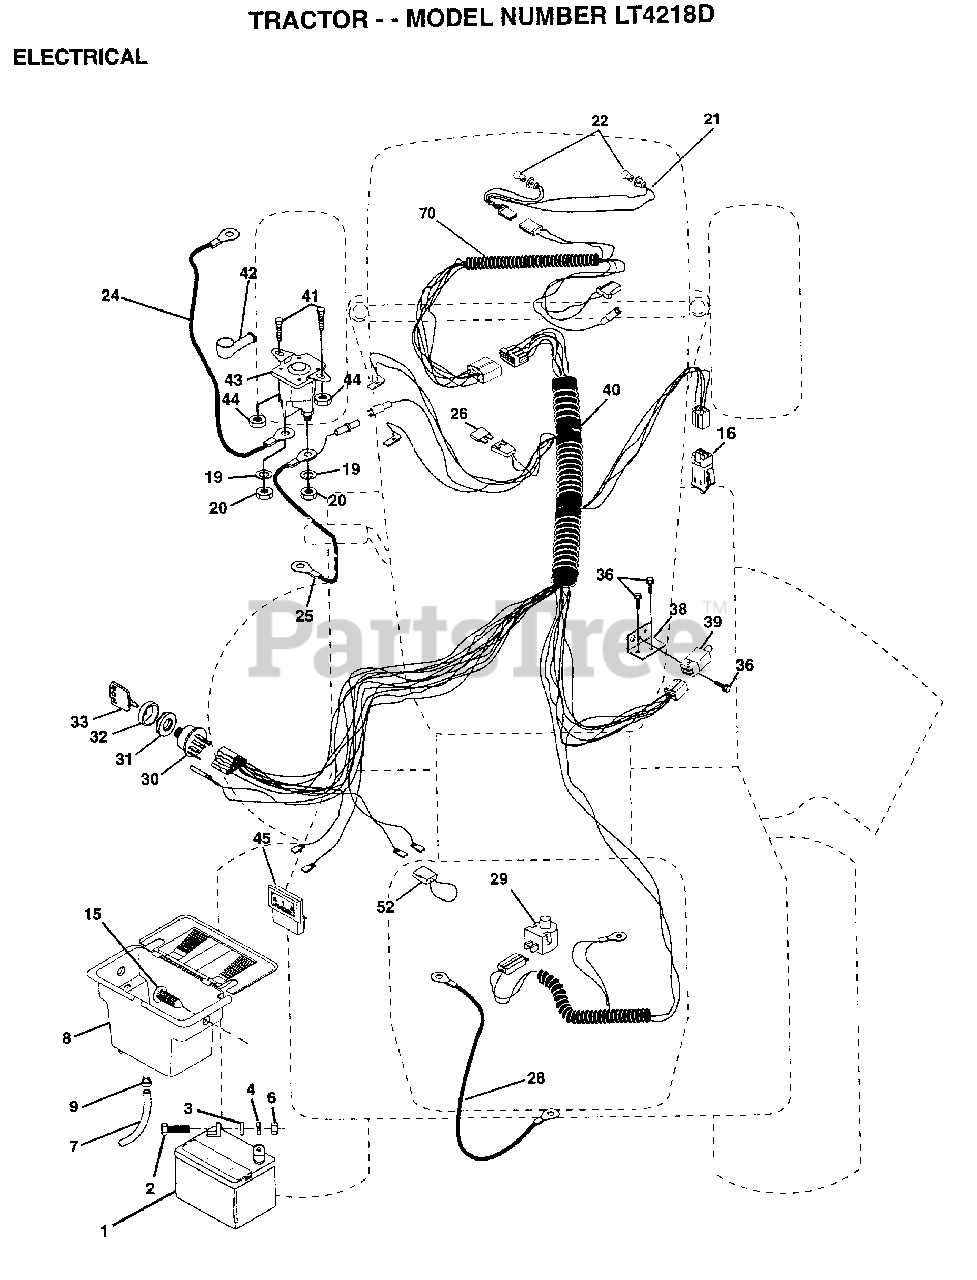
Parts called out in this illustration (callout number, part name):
2	BOLT LT
3	WASHER
4	LOCKWASHER
7	TUBE T
9	HOSE CLAMP T
15	FASTNER.SNAP-IN
16	SWITCH INTERLOCK
20	NUT
21	"HARNESS,LIGHT SOC"
22	HEADLAMP BULB
24	CABLE-BATTERY T
25	CABLE.BTRY.6GA.RD
26	FUSE HYT
28	CABLE T
29	SWITCH SEAT
30	SWITCH IGN 4POS
31	NUT IGNITION
32	COVER KEY SWITCH
33	KEY
36	SCREW
38	BRACKET SWITCH IN
39	SWITCH INTERLOCKT
40	HARNESS.IGNITION
41	BOLT HXHD FIN
44	NUT HXKEP 1/4X20
52	PROTECTION LOOP
70	HARNESS.ENG.LT.
